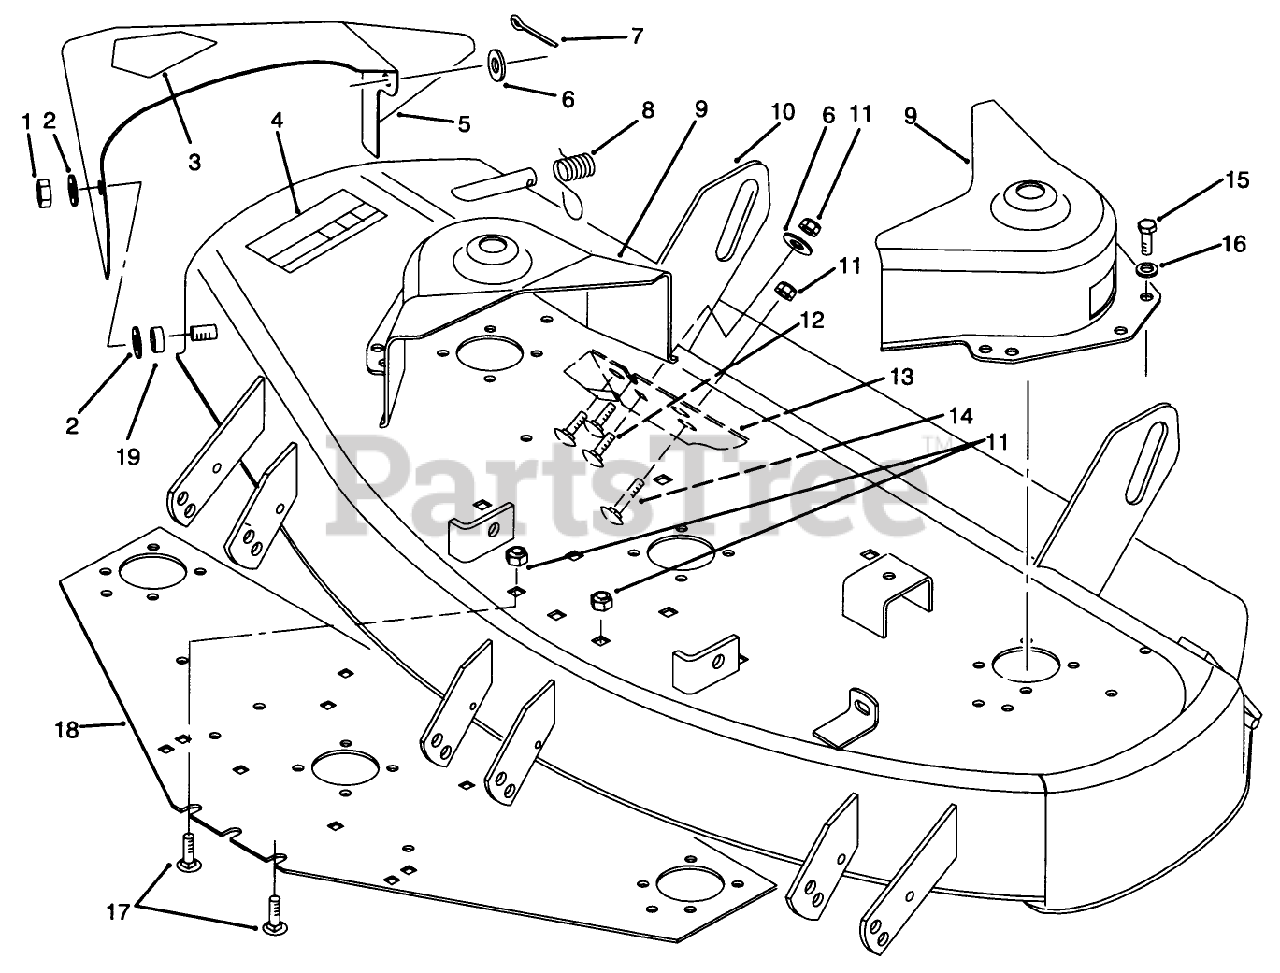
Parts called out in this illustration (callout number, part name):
1	Nut
2	Washer
3	DECAL-DANGER
4	DECAL-DANGER, THROWN OBJECT
5	Chute/Decal Assembly(Incl. Ref. #3)
6	WASHER-FLAT
7	PIN-COTTER
8	Spring
9	COVER-BELT
10	Deck/Safety Decal Assy. (Incl. Ref. #4, pg.1 Ref. #21, pg. 3)
11	NUT-LOCK, NI
12	SCREW-CARR
13	Plate-Wear
14	SCREW-CARR
15	Bolt
16	WASHER-FLAT
17	SCREW-CARR
18	Plate-Deck
19	BUSHING-PIVOT
